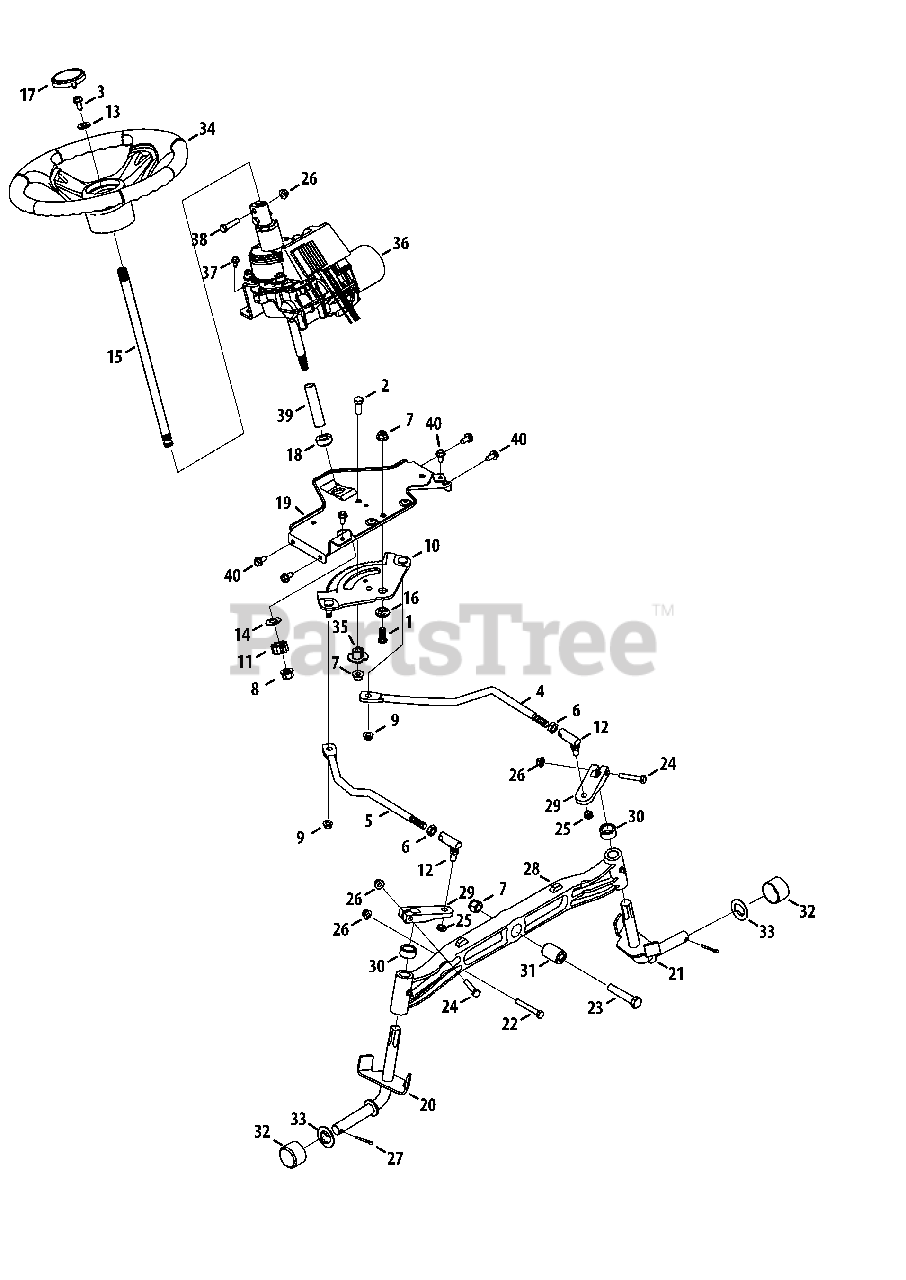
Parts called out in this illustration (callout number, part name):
1	Hex Screw, 3/8-16, 1.00, Gr5, Spec
2	Hex Screw, 3/8-16, 1.25, Gr5
3	Hex Screw, 5/16-18, .875, Gr5, Lock
4	Link, Drag LH
5	Link, Drag RH
6	Nut, Jam, 7/16-20, Gr2
7	Nut, Flange Lock, 3/8-16, Grf,
8	Nut, Flange Lock, 7/16-20, Grb, Lock
9	Nut, Flange Lock, 5/16-18, Gr5, Sd Lk
10	Gear, Steering
11	Gear, Pinion, Steering
12	Ball Joint, 7/16-20, Lock
13	Washer, Flat, .406 x .875 x .105
14	Washer, Flat, .51 x 1.12 x .06
15	Shaft, Steering, .625 OD x 14, Cub
16	Spacer, Shoulder, .385x 1.25 x .3025
17	Cover, Steering Wheel, Cub Cadet
18	Bearing, Flange, Hex 5/8 Pm
22	Hex Screw, 5/16-18, 2.25, Gr5, Std
23	Hex Screw, 3/8-16, 2.50, Gr5, Std
24	Hex Screw, 5/16-18, 1.75, Gr5, Std
25	Nut, Hex Lock, 3/8-24, Grb
26	Nut, Flange Lock, 5/16-18, Grf
27	Pin, Cotter, 5/32, 1.25
28	Axle, Pivot Bar, Cast
30	Spacer, .71 ID x .125 OD x .56
31	Spacer, .385 x 1.00 x 1.5075
32	Cap, Bumper
33	Washer, Flat, .350 x 1.559 x .062
34	Wheel, Steering, 3 Spoke, Softgrip
35	Spacer, .38 x 1.375, Spec
36	Transmission Steering Assembly, EPS
37	Screw, Self-tapping, 1/4-20 x .625
38	Hex Screw, 5/16-18 x 1.375, Gr5, Std
39	Spacer, .625 x .750 x 3.11
40	Screw, Self-tapping, 5/16-18, .750,
